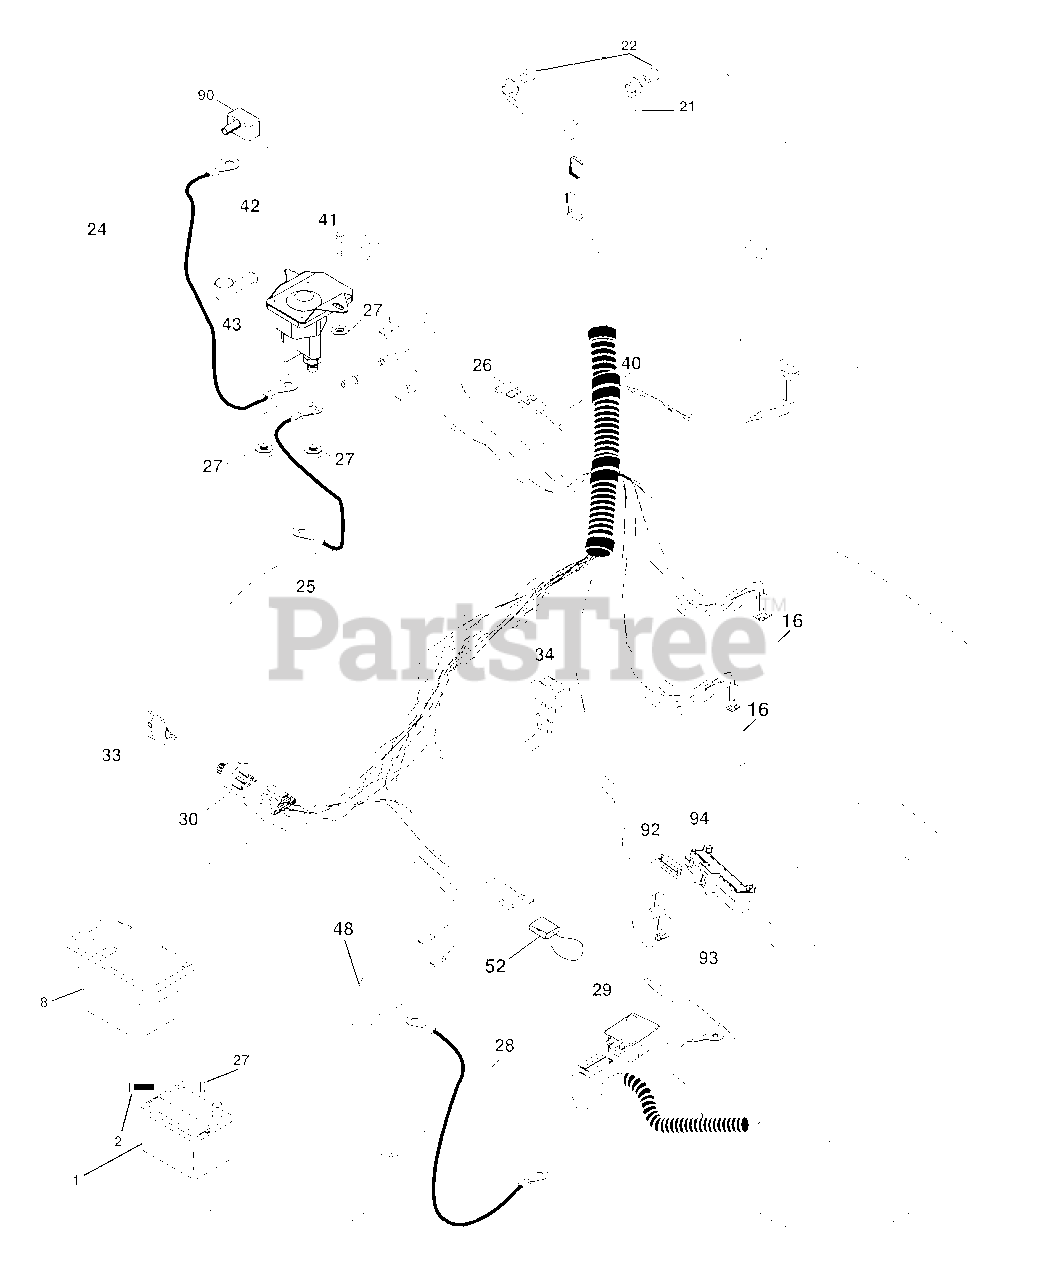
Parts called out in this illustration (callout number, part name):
1	Battery
2	Bolt Hex Hd 1/4-20 unc x 3/4
8	Box Battery
16	Switch Interlock
21	Harness Socket Light
22	Bulb, Light # 1156
24	Cable Battery
25	Cable Battery 6 Ga. Red w/16 wire 44"
26	Fuse
27	Nut Keps Hex 1/4-20 unc
28	Cable Ground 12" Blk 6 Ga.
29	Switch Seat
30	Switch Ign
33	Key Ign Molded Generic
34	Switch Light/Reset
40	Harness Ign
41	Bolt Fin Hex 1/4-20 unc x 1/2
42	Cover Terminal Red
43	Solenoid
48	Adapter Ammeter
52	Protection Loop
90	Cover Terminal
92	Harness Pigtail
93	Screw Plastite 10-14 x 2.0
94	Module Reverse ROS
